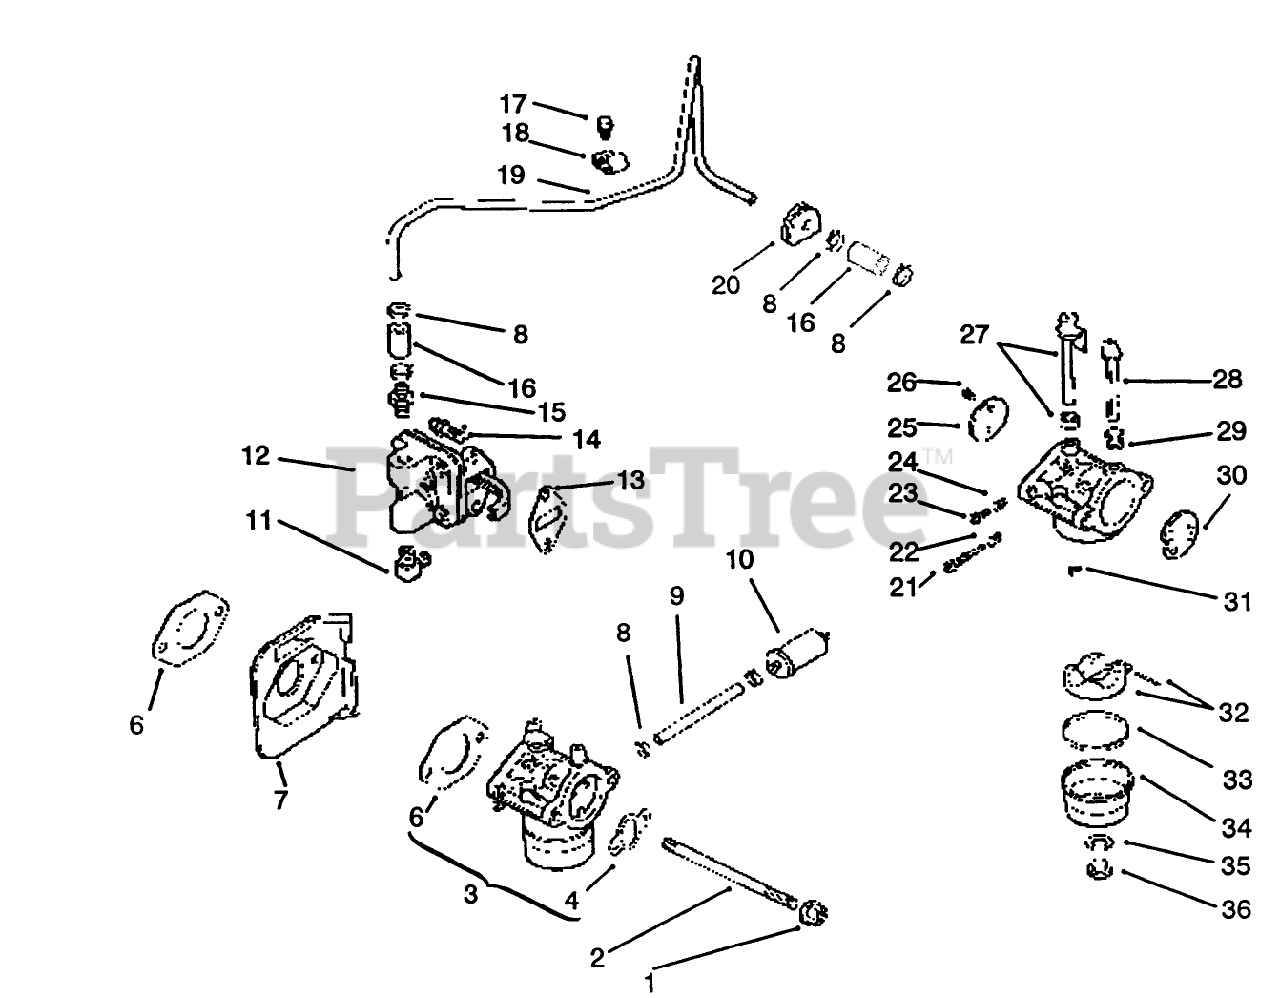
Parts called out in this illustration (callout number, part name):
2	Stud M6x1.0x110 (Only On: 72042,72043,72062,72063)
3	Kit-Carb INCL 4/6/21 -36 (Only On: 72042,72043,72062,72063)
4	Gasket-Air Cleaner (Only On: 72042, 72043, 72062, 72063)
6	Gasket-Carburetor (Only On: 72042, 72063, 72062, 72043)
7	Deflector-Heat (Only On: 72042,72043,72062,72063)
8	Clamp
9	Line-Fuel 3" (Only On: 72042, 72063, 72062, 72043)
10	Filter-Fuel (Only On: 72042,72043,72062,72063)
11	Connector
12	Kit-Pump INCL 13-14 (Only On: 72042,72043,72062,72063)
13	Gasket-Fuel Pump (Only On: 72042,72043,72062,72063)
14	Screw
15	Connector
16	Line-Fuel 1.25 Inch (Only On: 72042,72043,72062,72063)
18	Clamp-Fuel Line (Only On: 72042, 72063, 72062, 72043)
19	Line-Fuel (Only On: 72042,72043,72062,72063)
20	Grommet (Only On: 72042, 72063, 72062, 72043)
21	Needle-Idle Fuel Adjust (Only On: 72042, 72063, 72062, 72043)
22	Spring-Idle Fuel (Only On: 72042, 72063, 72062, 72043)
23	Screw-Idle Speed Adjust (Only On: 72042,72043,72062,72063)
24	Spring-Idle Fuel (Only On: 72042, 72063, 72062, 72043)
25	Plate-Throttle (Only On: 72042,72043,72062,72063)
26	Screw-Throttle Plate (Only On: 72042,72043,72062,72063)
27	Shaft-W/Lever Seal (Only On: 72042, 72063, 72062, 72043)
28	Shaft-Choke (Only On: 72042. 72063, 72062, 72043)
29	Spring-Choke Return (Only On: 72042,72063, 72062, 72043)
30	Plate-Choke (Only On: 72042, 72063, 72062, 72043)
31	Jet-Main (Only On: 72042, 72063, 72062, 72043)
32	Kit-Float (Only On: 72042,72043,72062,72063)
33	Gasket-Bowl (Only On: 72042,72043,72062,72063)
34	Bowl-Fuel (Only On: 72042, 72063, 72062, 72043)
35	Gasket-Bowl Screw (Only On: 72042, 72063, 72062, 72043)
36	Screw-Fuel Bowl (Only On: 72042, 72063,72062, 72043)
